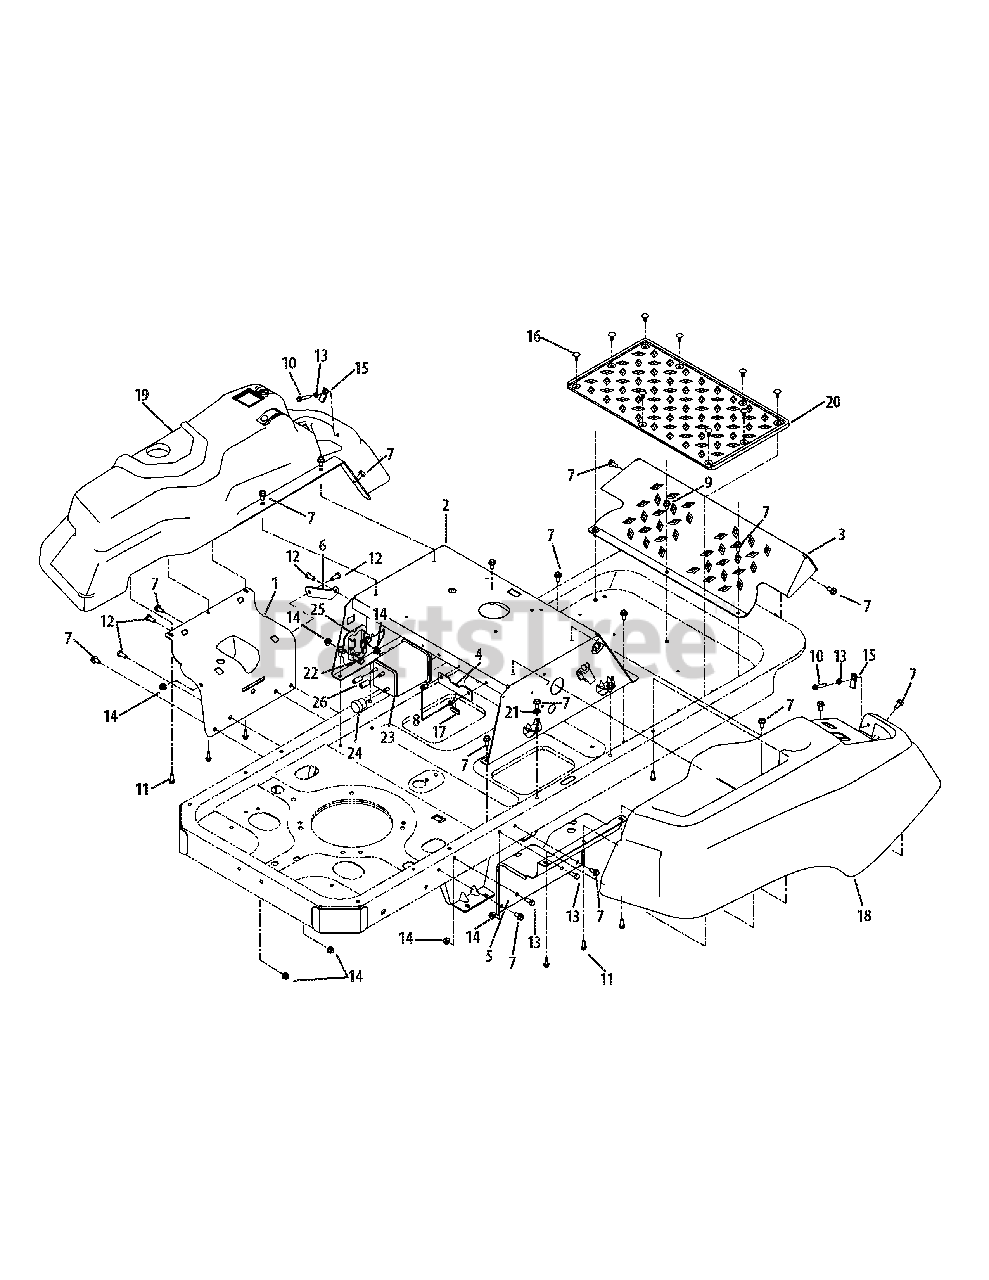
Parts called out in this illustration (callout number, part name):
1	Console Bracket Assembly
2	Seat Frame Assembly
3	Foot Rest Bracket
4	Battery Hold-Down Bracket
5	Console Mount Bracket
6	Fuel Tank Support Bracket
7	Hex Washer Screw, 5/16-18 x .750
8	Hex Washer Screw, 1/4-20 x .500
9	Hex Washer Screw, 5/16-18 x .625
10	Hex Washer Screw, 1/4-20 x 1.500
11	Hex Washer Screw, 1/4-15 x .750
12	Hex Screw, 5/16-18 x .75
13	Jam Nut, 1/4-20
14	Flange Lock Nut, 5/16-18
15	Speed Nut, 1/4-20
16	Ratchet Clip
17	Trim Strip
18	RH Console
19	LH Console
20	Foot Pad
21	Lock Washer, 3/8
22	Hex Washer Screw, 5/16-18 x .875
23	Carbon Canister
24	Canister Filter Vent
25	Canister Bracket Adapter
26	Fuel Hose
